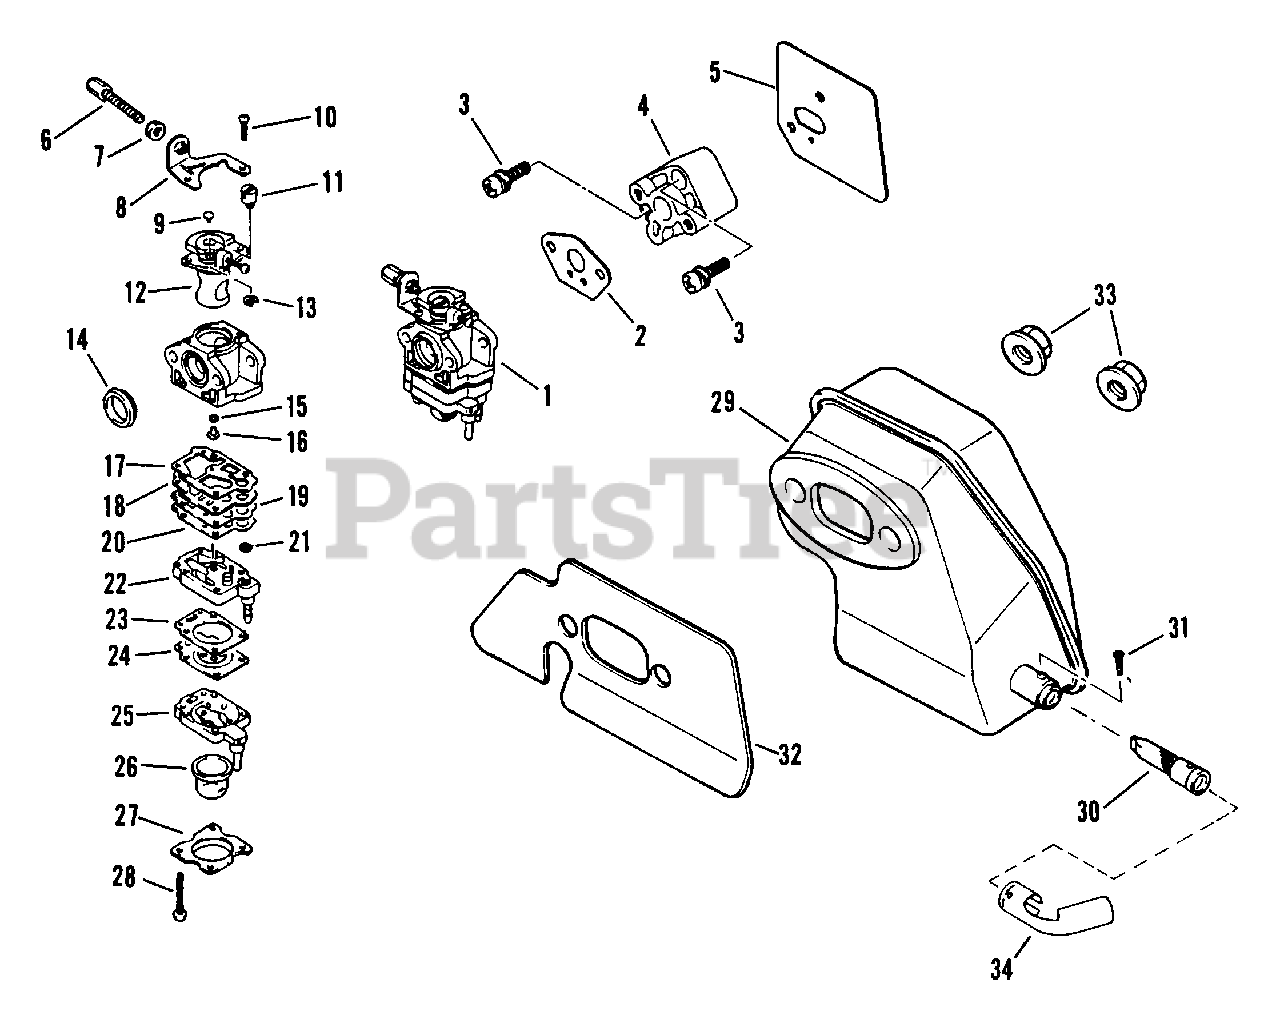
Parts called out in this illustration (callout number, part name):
1	ASSEMBLY, Carburetor
2	GASKET, Carburetor
3	SCREW/WASHER
4	INSULATOR
5	GASKET, Insulator
7	NUT
8	BRACKET
11	HOLDER, Wire
12	VALVE, Throttle
14	PACKING
16	JET, Main
18	DIAPHRAGM
22	BODY, Pump
24	DIAPHRAGM
26	ASSEMBLY, Primer Pump
29	MUFFLER
30	SPARK ARRESTER
32	GASKET, Muffler
33	NUT, Flange
34	EXHAUST, Elbow
